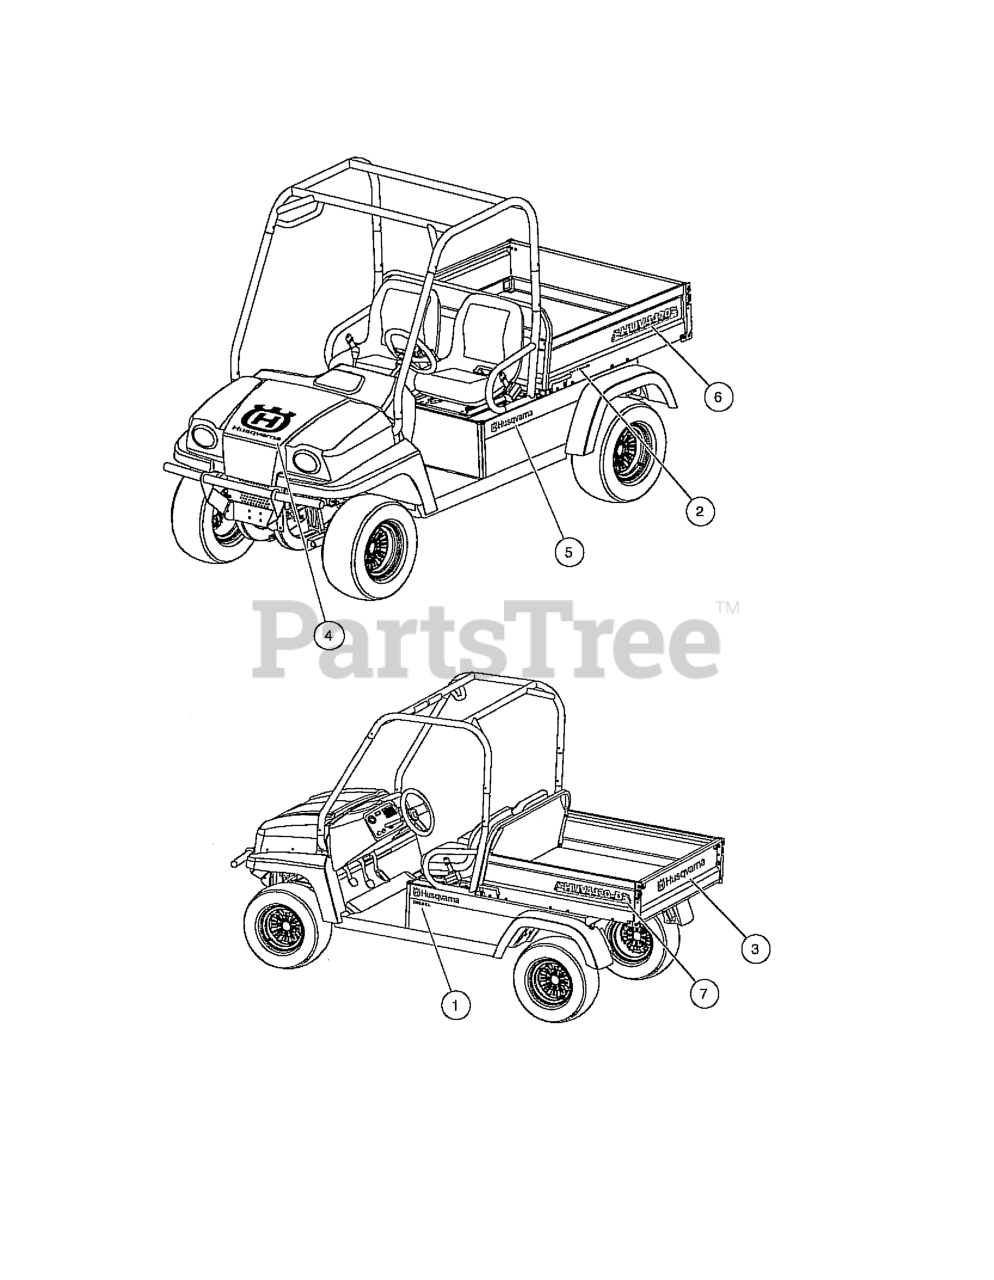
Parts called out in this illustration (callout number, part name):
1	DECAL, DIESEL
2	DECAL, HIGH CAPACITY
3	DECAL, TAILGATE,OEM
4	DECAL HOOD
5	DECAL SIDE PANEL
